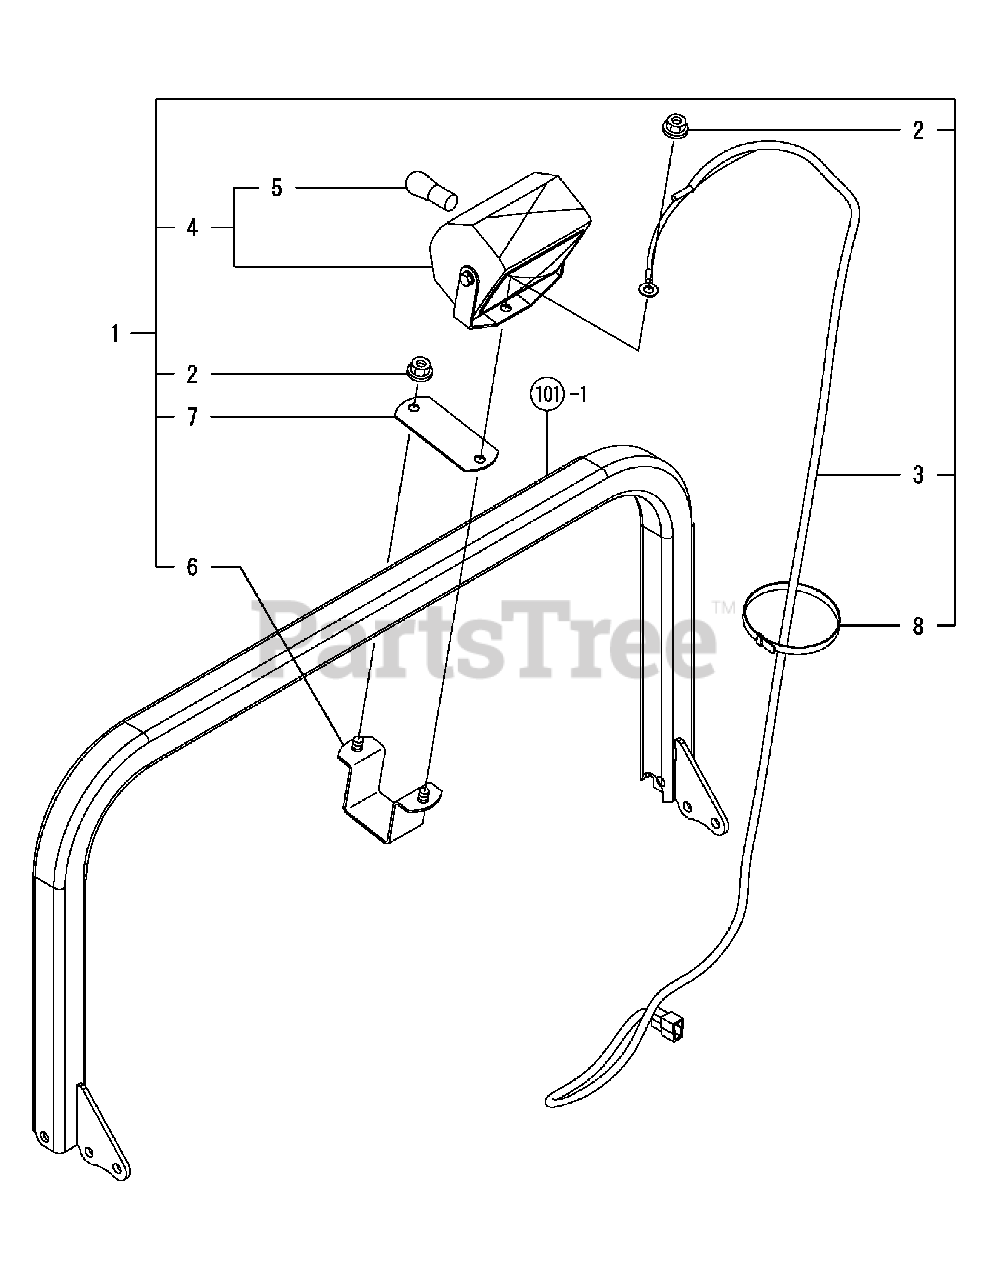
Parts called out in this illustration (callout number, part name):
1	LAMP KIT, WORK
2	NUT W/WASHER 8
3	CABLE,WORK LAMP
4	LAMP ASSY, WORKING
5	BULB 12V-18.4W
6	STAY A,WORK LAMP
7	STAY B,WORK LAMP
